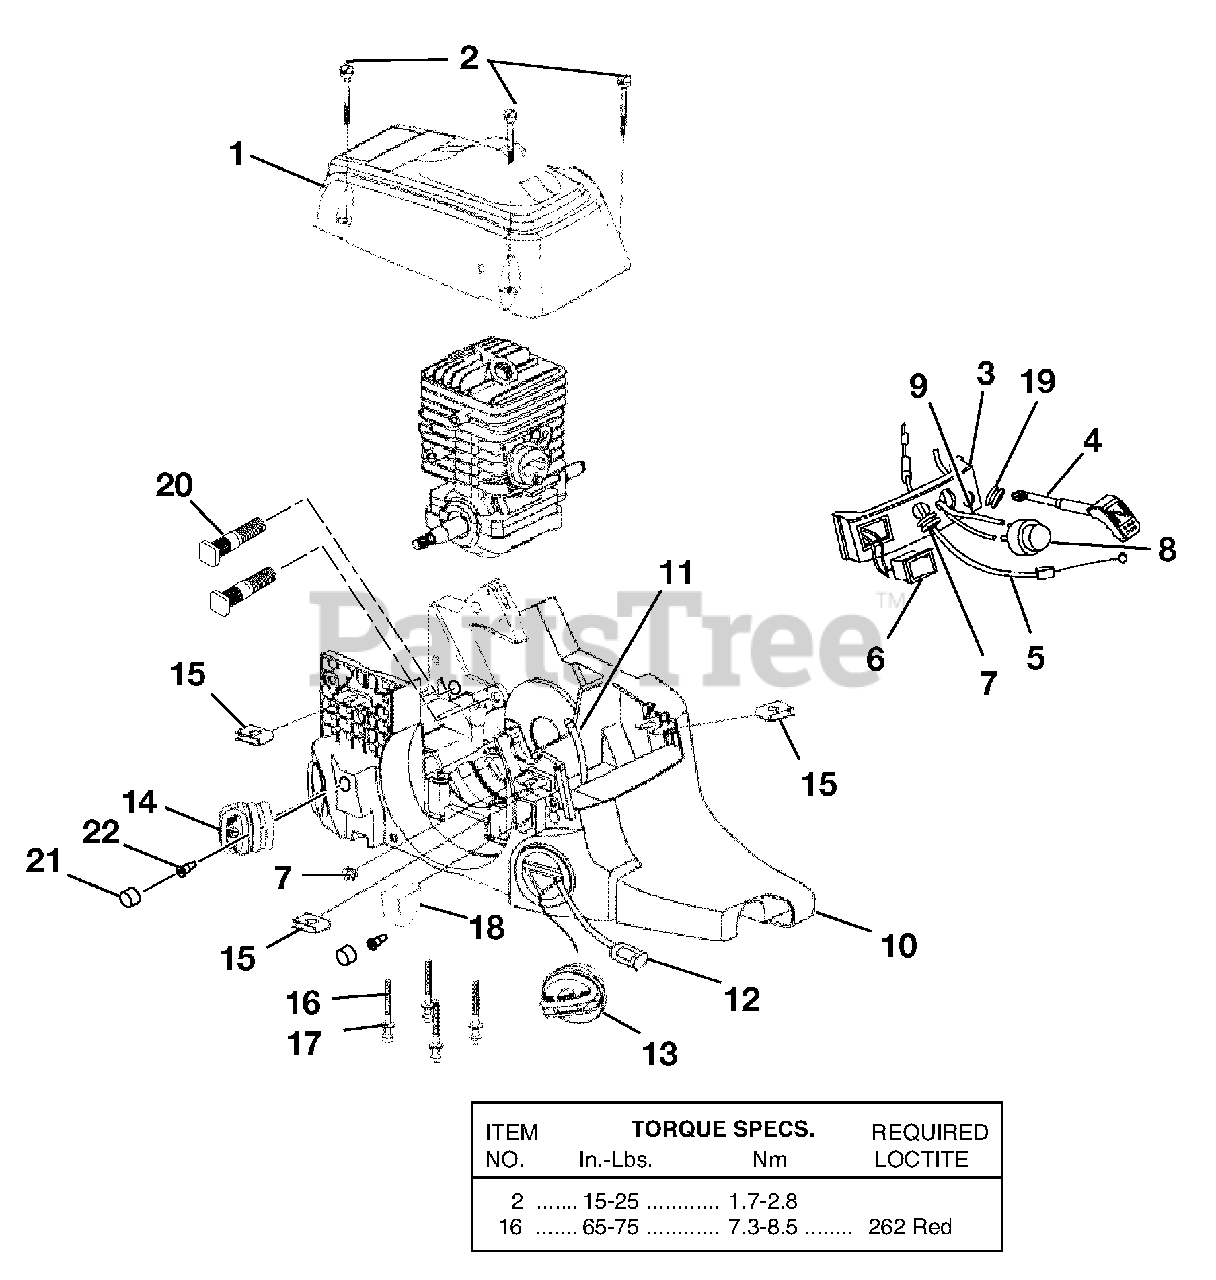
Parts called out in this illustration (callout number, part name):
1	Cylinder Cover
2	Screw-slotted Pan Head
3	Control Panel
4	Choke Rod
5	Throttle Cable
6	Rocker Switch
7	Split Grommet
8	Primer Bulb
9	Rubber Tubing (5-1/2 in.)
10	Chassis Assembly
11	Rubber Tubing (8-1/2 in.)
12	Fuel Filter
13	Fuel Cap, w/Retainer
14	Oil Cap, w/Retainer
15	Speed Nut (U-Type)
16	Screw, (10-24 x 2 in.)
18	Pre Filter
20	Guide Bar Bolt
22	Duck Bill Valve
